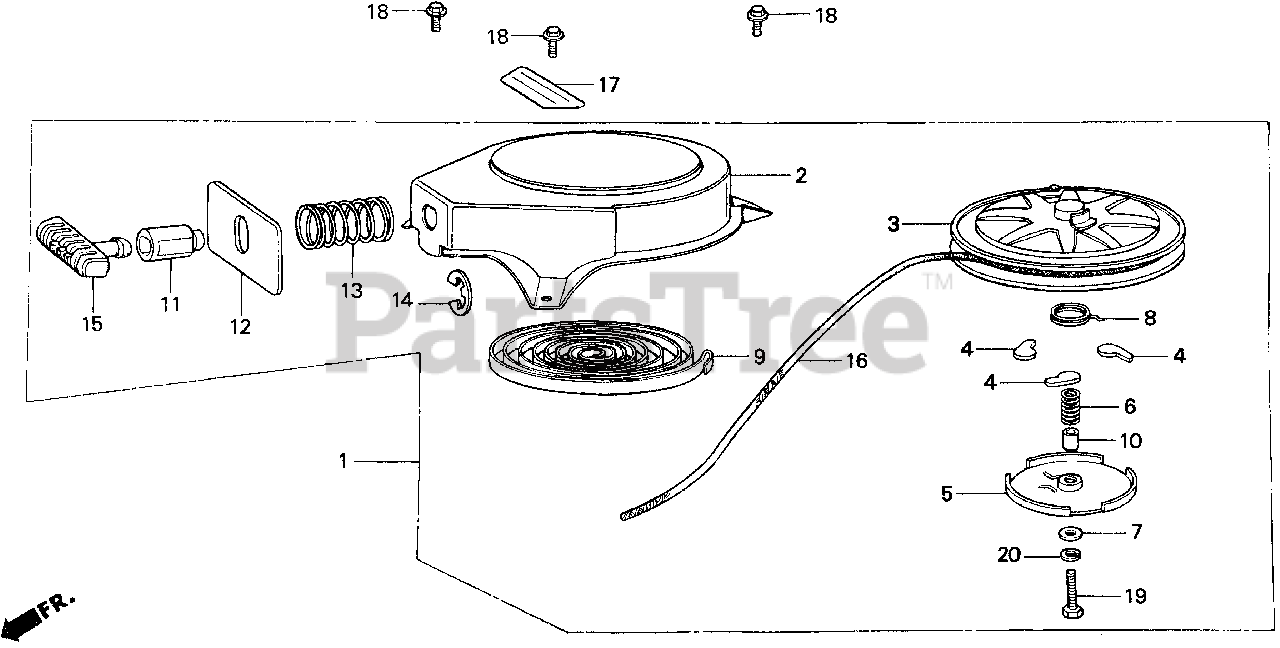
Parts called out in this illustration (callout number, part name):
1	STARTER ASSY., RECOIL
2	CASE, RECOIL STARTER
3	PULLEY, RECOIL STARTER
4	RATCHET, STARTER
5	PLATE, FRICTION
6	SPRING, FRICTION
8	SPRING SET
9	SPRING, RECOIL STARTER
11	GUIDE, ROPE
12	PLATE, SEAL
13	SPRING, SEAL PLATE
15	GRIP, STARTER
16	ROPE, RECOIL STARTER (#4X65") (NA USE ALT:08540-ZG921-11)
17	MARK, RECOIL STARTER CAUTION
18	BOLT, FLANGE (6X12)
19	BOLT, HEX. (6X25)
20	WASHER, SPRING (6MM)
